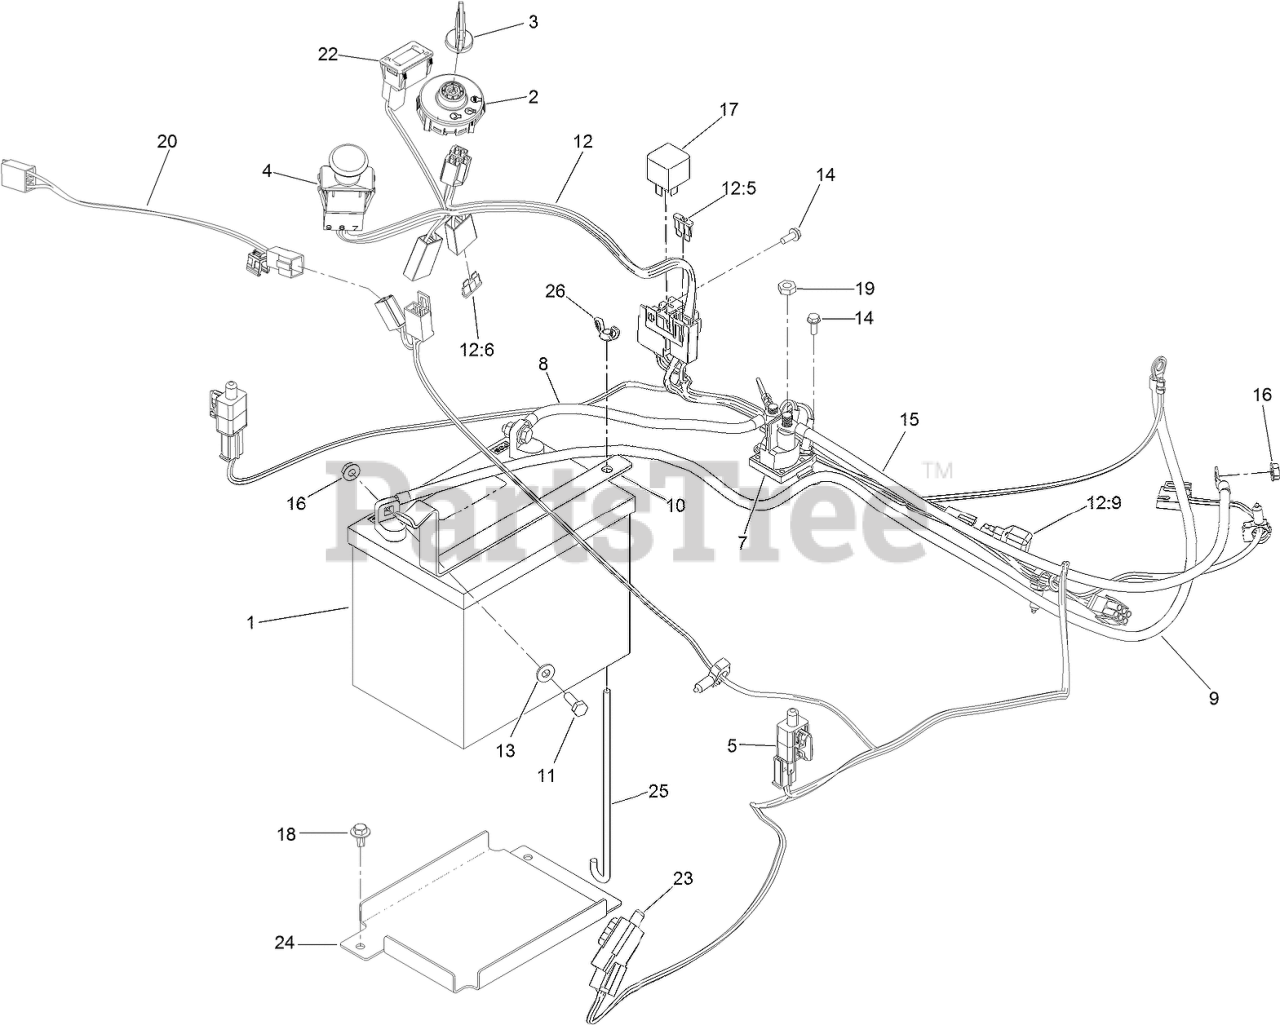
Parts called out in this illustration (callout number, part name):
1	BATTERY
2	SWITCH-IGNITION
3	KEY-IGNITION
4	SWITCH-PTO
5	SWITCH
7	SOLENOID
8	CABLE-BATTERY, POSITIVE
9	CABLE-BATTERY, NEGATIVE
10	STRAP-BATTERY
11	SCREW-HH
12	HARNESS-WIRE
12:5	FUSE-BLADE, 30 AMP
12:6	FUSE-BLADE, 25 AMP
13	WASHER-FLAT
14	SCREW-TAPTITE
15	WIRE-21 INCH
16	NUT-HF
17	RELAY
18	SCREW-HHFTF
19	NUT-JAM
20	HARNESS-WIRE
22	HOURMETER
23	SWITCH-REVERSE
24	TRAY-BATTERY
25	BOLT-HOLDDOWN
26	WINGNUT
